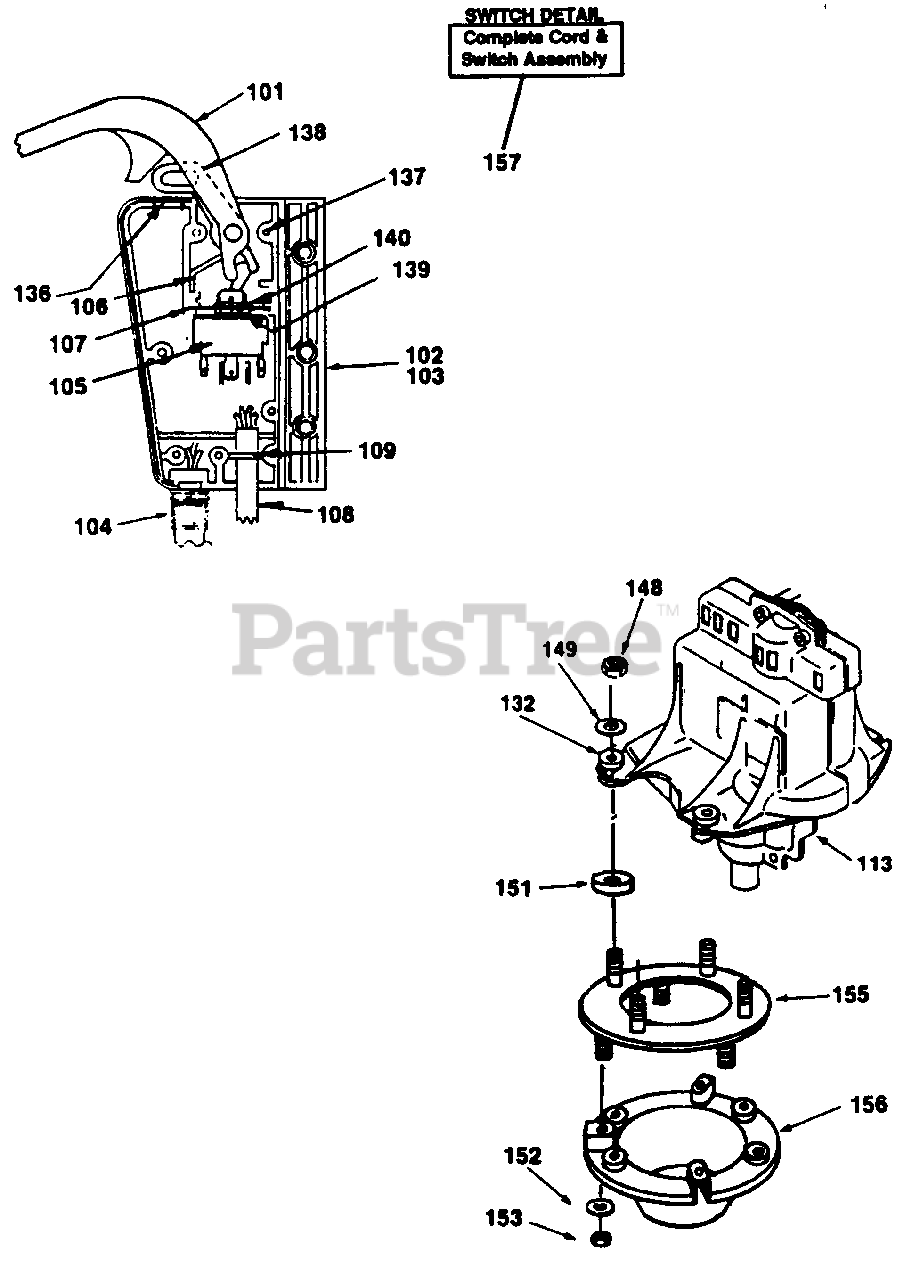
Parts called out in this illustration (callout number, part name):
101	Handle - Switch
102	Housing - Upper Half
103	Housing - Lower Half
104	Plug Assembly
105	Switch
106	Spring - Switch Handle
107	Switch Mount Plate
108	Cord Assembly
109	Cord Restraint
113	Complete Motor & Switch Ass'y.
132	Insulator- Motor Housing
136	Hole plug
137	Screw - Switch Box
138	Interlock Trigger
139	Washer
140	Nut
148	Nut 1/4-20 Locking
149	Flatwasher 1/4"
151	Spacer
152	Flatwsher 5/16"
153	Nut 5/16-18 Locking
155	Motor Mounting Plate Ass'y
156	Motor Shield
157	Cord & Switch Box Ass'y. (Complete)
